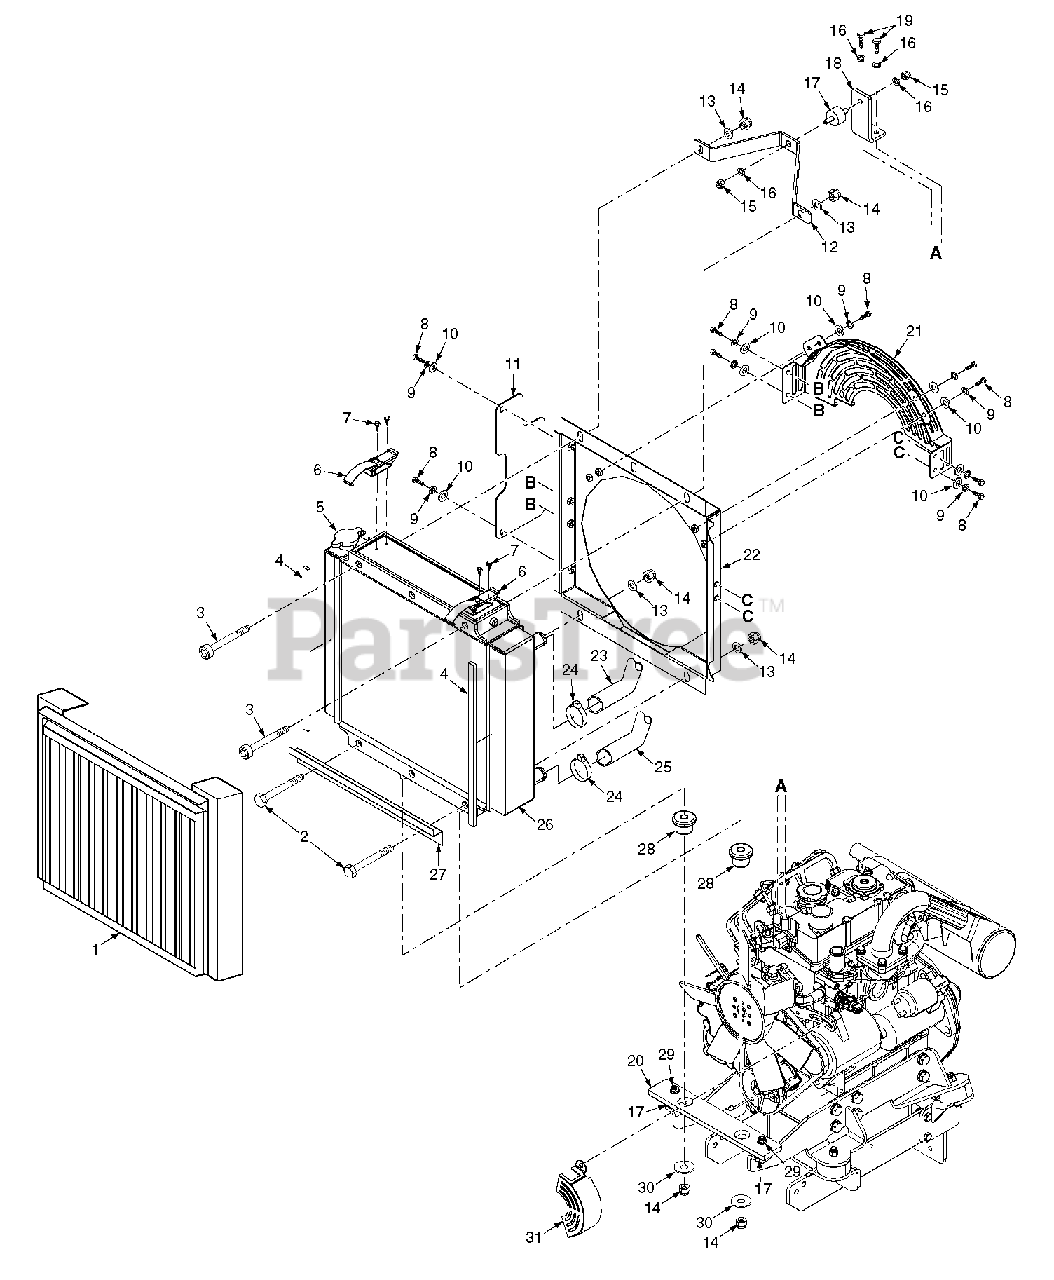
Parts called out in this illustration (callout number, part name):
1	Debris Screen Weldment
2	Bolt, Hex Head 3/8-16 x 4-1/2"
3	Bolt, Socket Head 3/8-16 x 4-1/2"
4	Foam, Seal, 1/2" x 1/4" x 14-1/2"
5	Radiator Cap
6	Latch, Hood
7	Screw, #10-32 x .56
8	Bolt, Hex Head 1/4-20 x .63"
9	Lockwasher, 1/4" Spring
10	Flatwasher, 1/4" (.312 x .750 x .065)
11	Heatshield
12	Bracket, Radiator Support
13	Flatwasher, 3/8" (.391 x .938 x .105)
14	Nut, Elastic Stop 3/8-16
15	Nut, 5/16-18
16	Lockwasher, 5/16"
17	Mount, Radiator Isolation
18	Bracket, Radiator Mount to Engine
19	Bolt, Hex Head M8 x 1.25 x 25
20	Mount, Radiator
21	Guard, Fan
22	Shroud Weldment, Radiator
23	Hose, Upper Radiator
24	Clamp, Hose, 1-3/4"
25	Hose, Lower Radiator
26	Radiator
27	Support, Debris Screen
28	Mount, Radiator Isolation
29	Nut, Hex Serrated Flange 5/16-18
30	Flatwasher, 3/8" (.406 x 1.50 x 7 ga)
31	Guard, Belt
